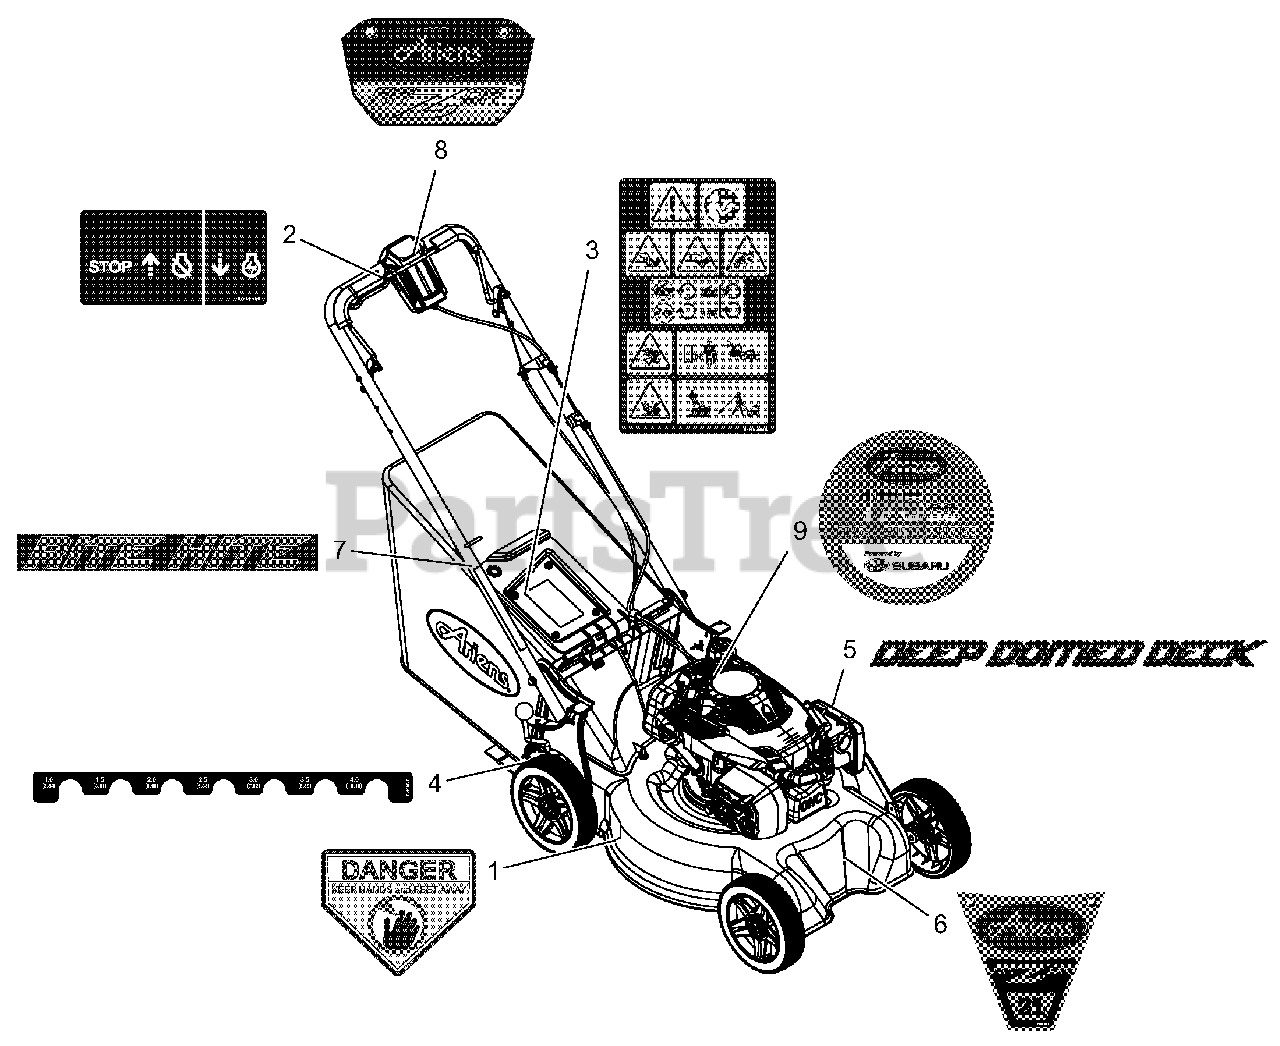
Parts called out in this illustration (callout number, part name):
1	DECAL, DANGER
2	DECAL - ENGINE CONTROL
3	DECAL,MAIN SAFETY_WAW LM
4	DECAL, HOC
5	DECAL, DEEP DOME DECK
6	DECAL, ARIENS RAZOR STYLE
7	DECAL, RITE HITE
8	DECAL, ARIENS RAZOR - SMALL
9	DECAL, ENGINE STYLE, ARIENS CE
